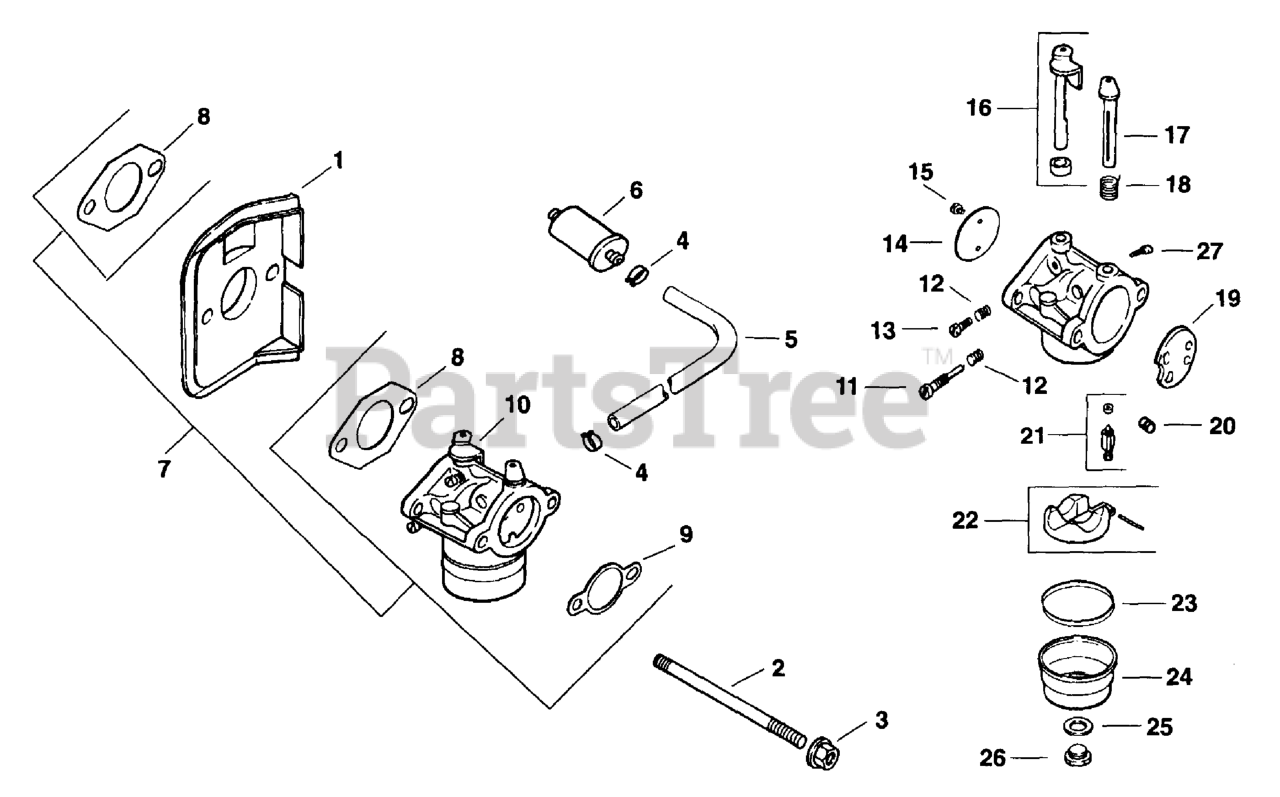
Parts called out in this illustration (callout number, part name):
1	DEFLECTOR - USE 12 265 04
2	Stud, carburetor M6x1.0x122.8
3	Nut, hex. flange M6x1.0
4	CLAMP, HOSE 1/2" USE 25 237 14-S
5	LINE - DISCONTINUED
7	CARBURETOR - USE 12 853 57
8	GASKET, CARBURETOR
9	GASKET, AIR CLEANER BASE
10	KIT, CARBURETOR w/GASKETS
11	NEEDLE - DISCONTINUED
15	SCREW, VALVE
16	SHAFT, THROTTLE
20	JET - DISCONTINUED
21	Needle and Seat
22	KIT, REPAIR FLOAT
23	GASKET, FUEL BOWL
26	SCREW, FUEL BOWL RETAINER
